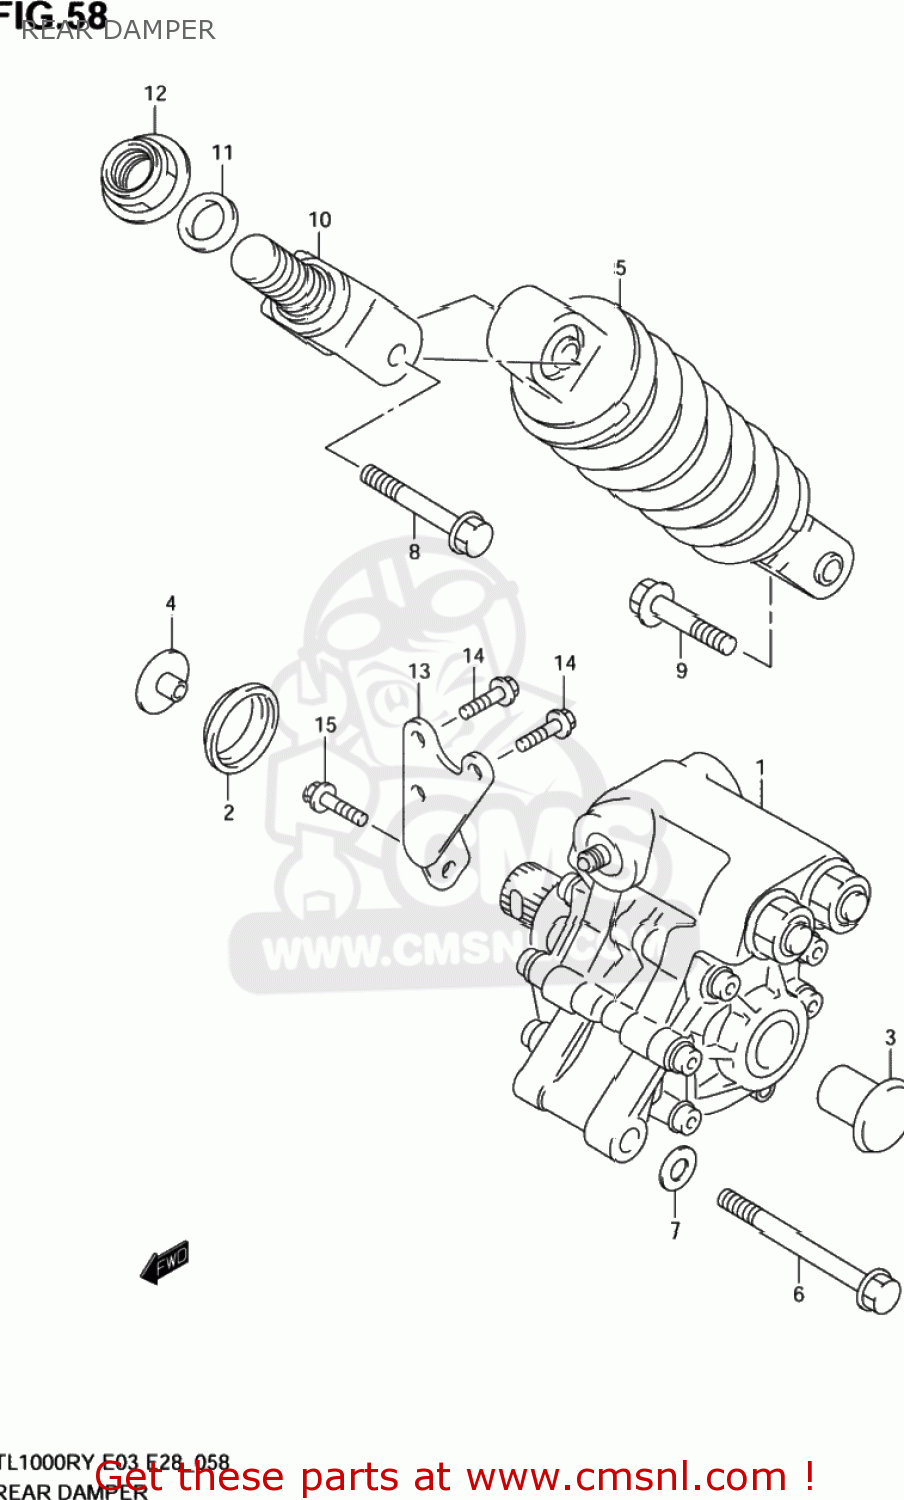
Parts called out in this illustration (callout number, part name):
1	DAMPER ASSY,RR
2	CAP
3	CAP
4	CAP(OD:19.5)
5	UNIT ASSY,RR SPRING
6	BOLT
7	WASHER
8	BOLT(10X52)
9	BOLT(10X48)
10	BRACKET,RR SHOCK ABSORBER UPR
11	SPACER,BRACKET(20.4X29X7.2)
12	NUT
13	BRACKET,RR DAMPER
14	BOLT
15	BOLT
